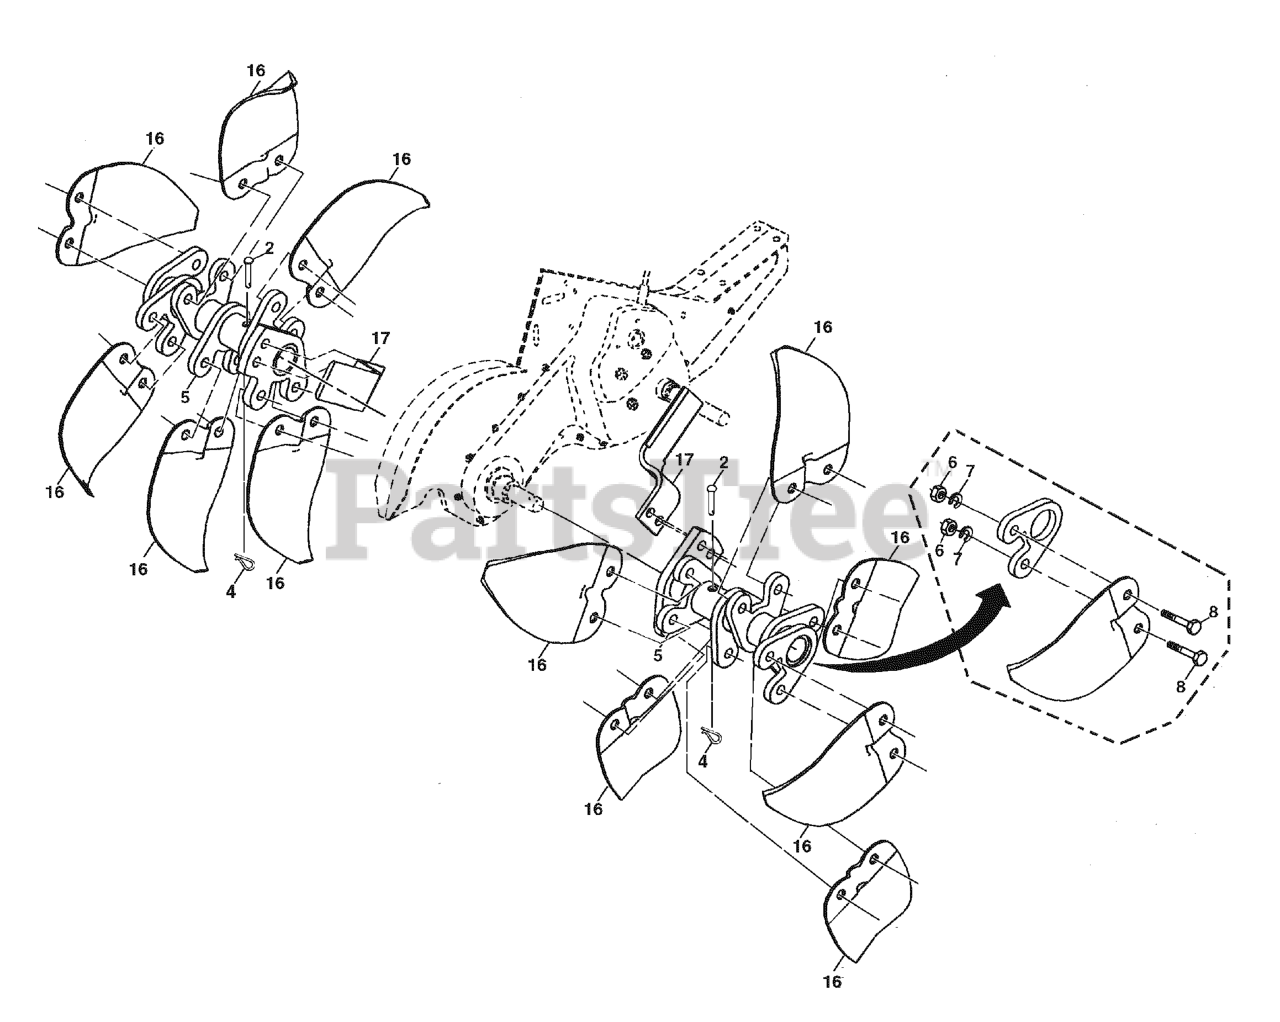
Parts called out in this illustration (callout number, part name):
2	PIN RETAINING SCREW
4	SPRING RETAINER
5	HUB.ASM.DRT17.2004 (CMPL KIT)
6	NUT
7	WASHER, LOCK 3/8
8	BOLT.HEX.001X20.37-24X1.ZINC
16	TINE.SPADE
17	TINE.CLEANING BLACK
